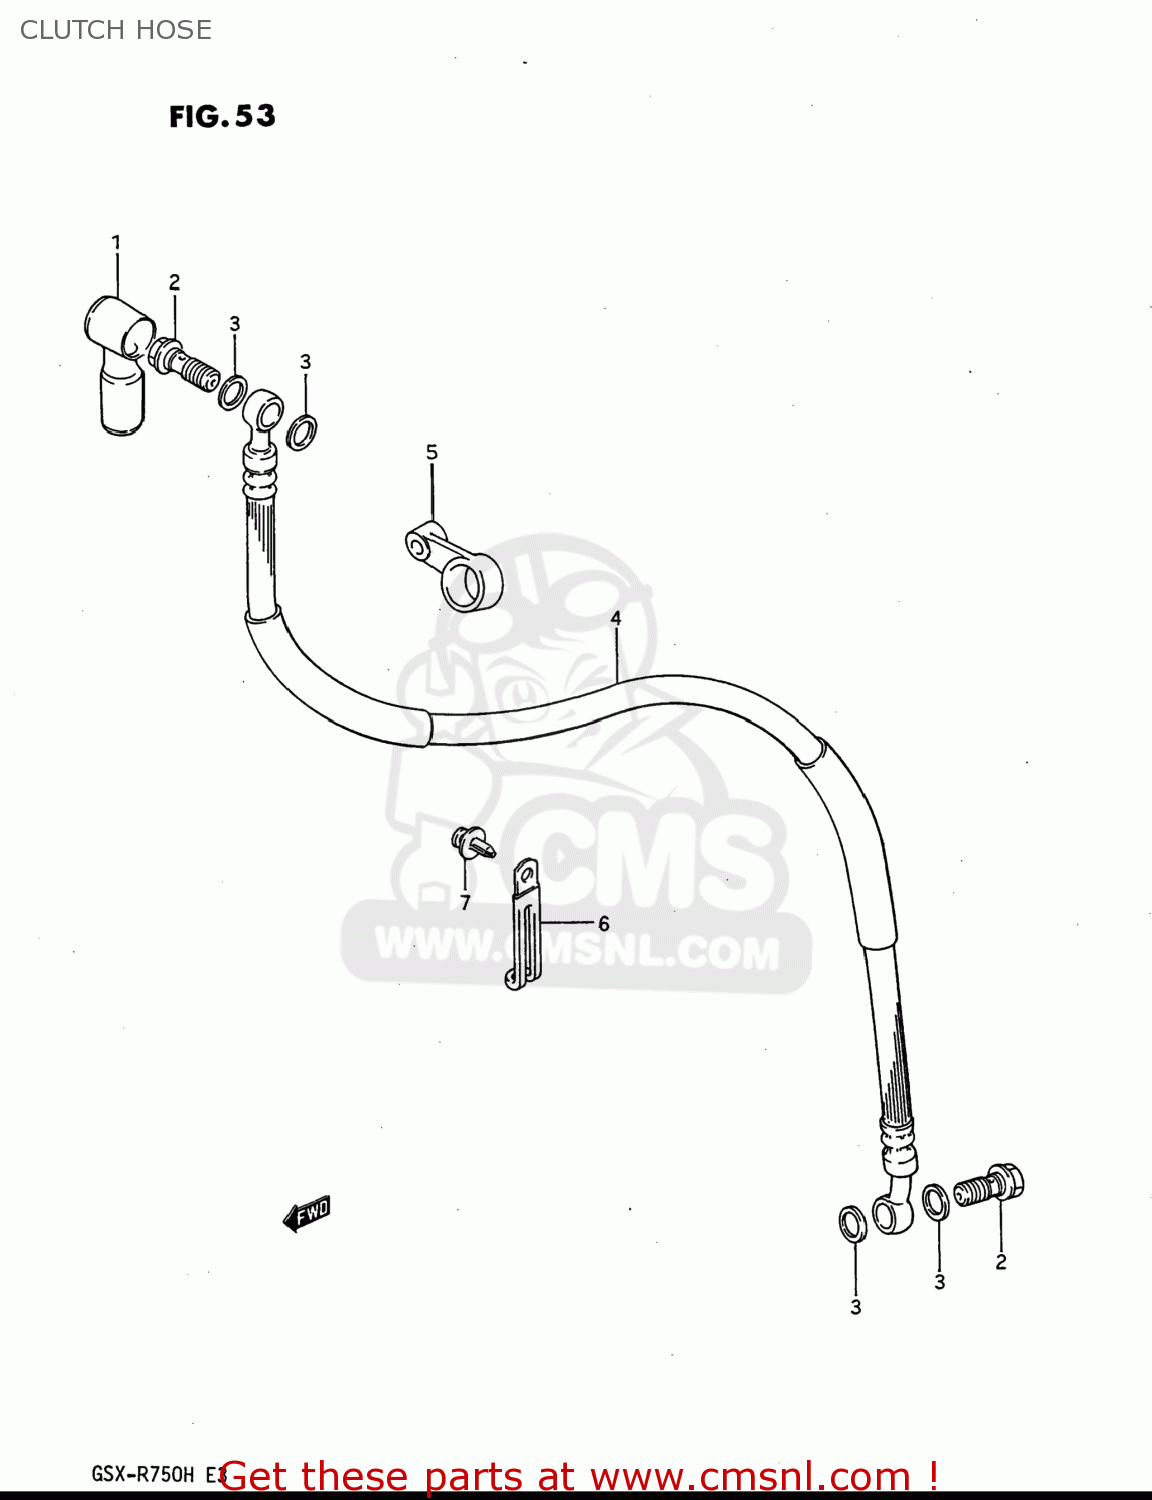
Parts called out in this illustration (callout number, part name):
1	BOOT,MASTER CYLINDER
2	BOLT UNION
3	WASHER(10X15X1.5)
4	HOSE,CLUTCH
5	CLAMP,CLUTCH HOSE NO.2
6	CLAMP
7	CLIP
